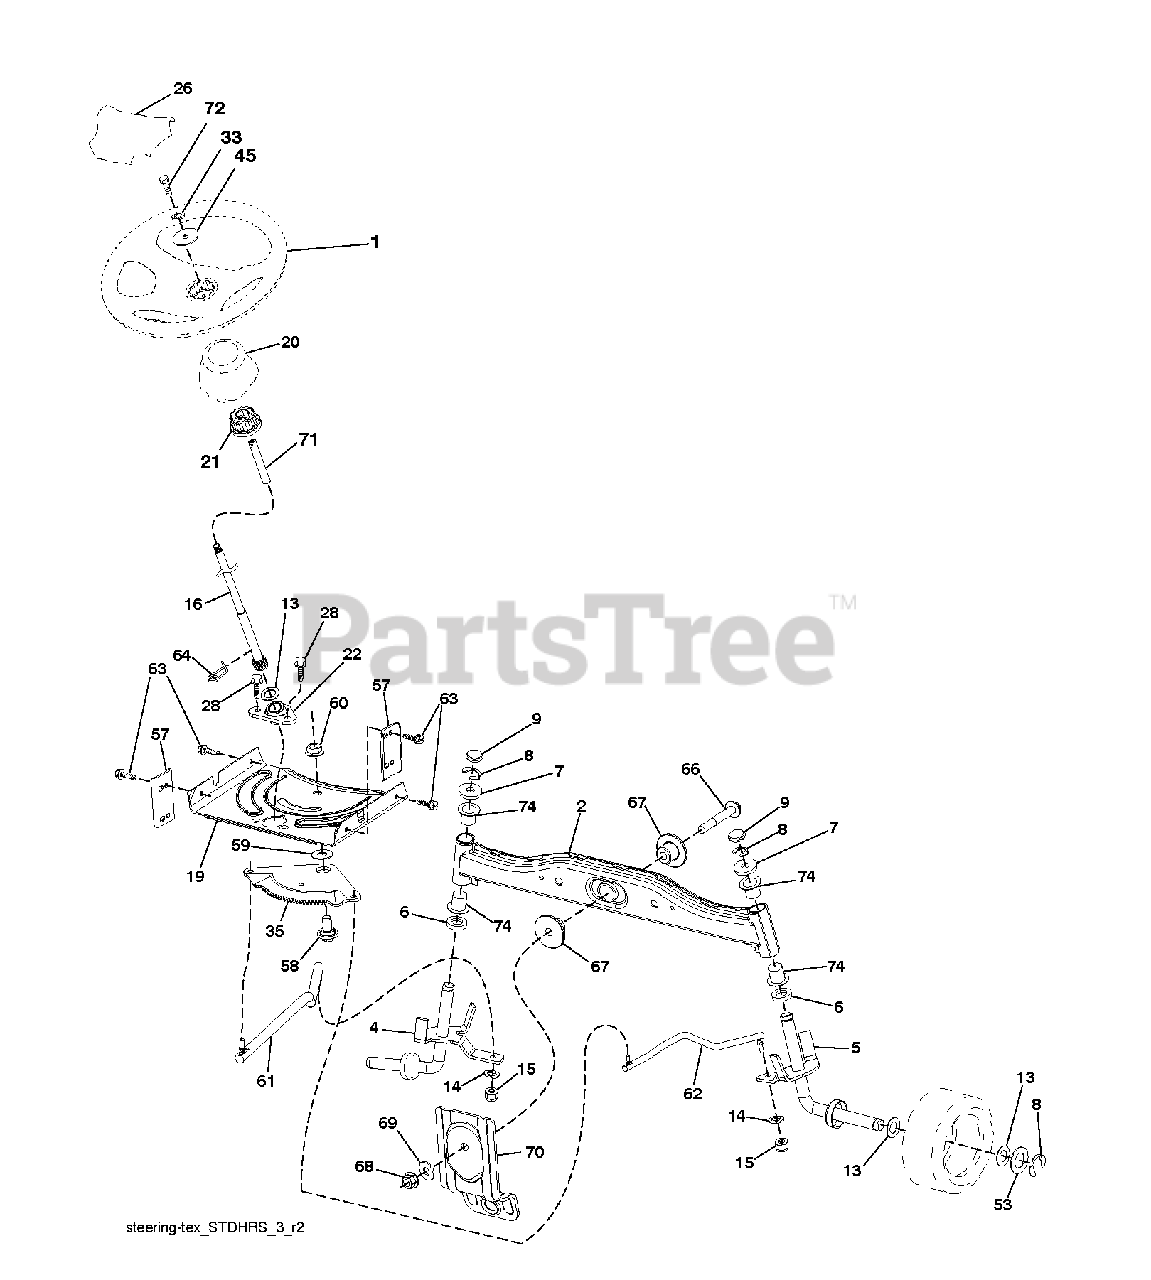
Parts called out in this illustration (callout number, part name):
1	WHEEL.STEERING.STDSRR.BLK/OV
2	AXLE HALF ASM-WELDED
4	SPINDLE.WELDED.LH.15"TEX
5	SPINDLE.WELDED.RH.15"T
8	RING CLIP
9	CAP.SPINDLE.BLACK
14	WASHER, LOCK 3/8
15	NUT CROWNLOCK 3/8-24
16	SHAFT.STEER.3/4.PLATED.TEX
19	PLATE.STEER.DDL.NLT/NG
20	BOOT STEERING BLACK
21	ADAPTER, WHEEL STNG..
22	STEERING.SUPT.LOWER.
26	INSERT, WHEEL STEERING
28	SCREW, 3/8-16X3/4
33	LOCKWASHER
35	GEAR.SECTOR.PLATE.DDL.
45	WASHER.11/32
53	WASHER.HARDENED
57	BRACKET.UPSTOP.TEX
58	BOLT.SHOULDER.SECTOR.P
59	WASHER.THURST.SECTOR.S
60	NUT FLANGE LOCK 5/8-11
61	DRAGLINK.LH.BALLSTUD.D
62	DRAGLINK.RH.BALLSTUD.D
63	SCREW
64	RETAINER.CLIP.SPRING.S
66	BOLT HEX FGHD 7/16-14 X 3 SERR
67	BUSHING.PM.FRONT AXLE
68	NUT.LOCK.FLANGE.7/16
69	WASHER.1.5X.505X.118
70	BRKT.DECK.SUSPENSION.F
71	SHAFT.EXTEN.STRG.SPLINE
72	BOLT 5/16-18 X 4 W/PATCH
74	Steering Column Bearing
